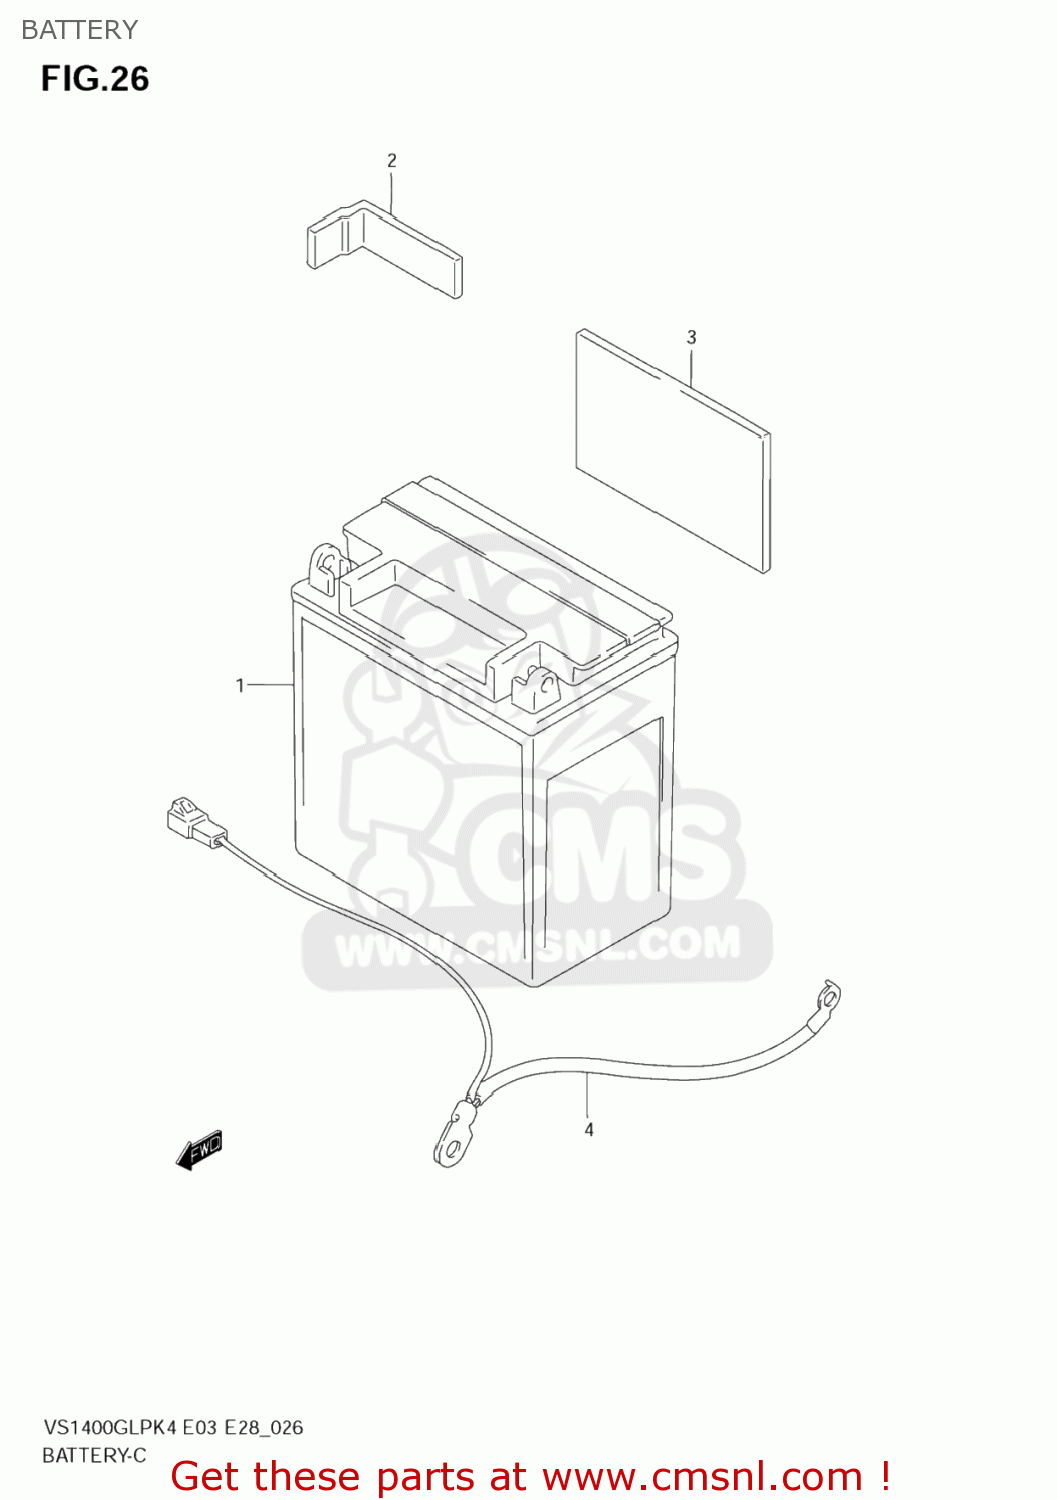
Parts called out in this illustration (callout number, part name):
1	BATTERY ASSEMBLY 12V14AH,F
2	PROTECTOR(80X80X2)
3	PROTECTOR(170X95X3.0)
4	WIRE,BATTERY MINUS LEAD
